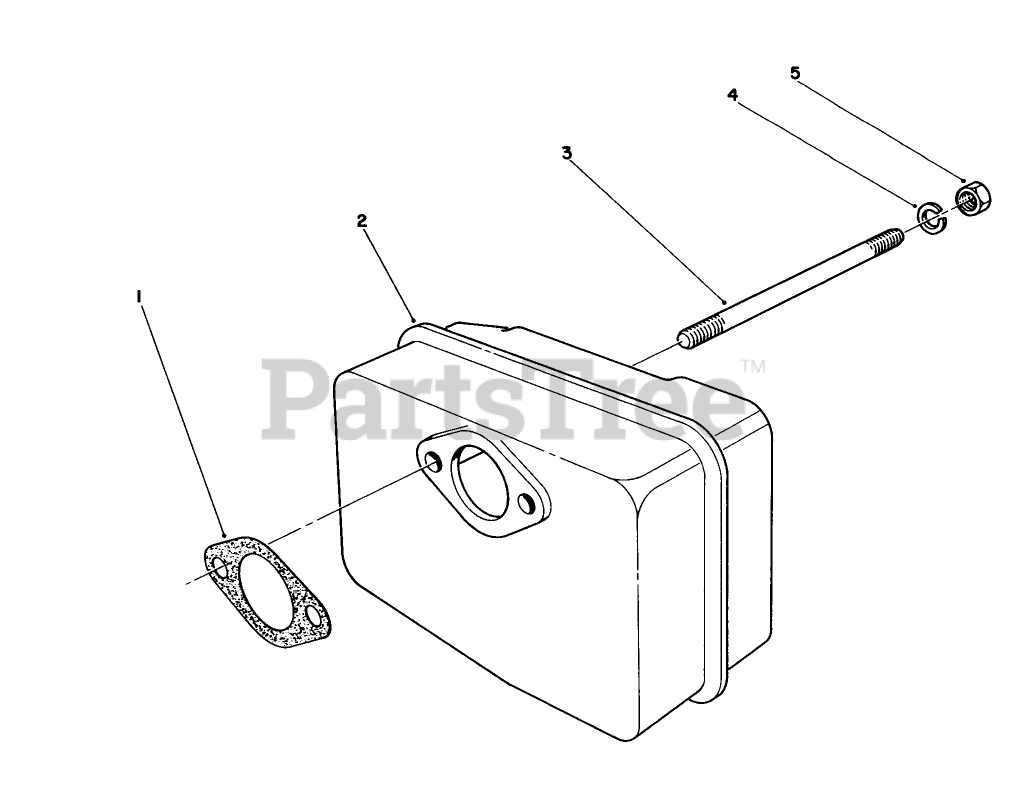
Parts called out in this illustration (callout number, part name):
1	GASKET
2	MUFFLER
4	WASHER-LOCK
